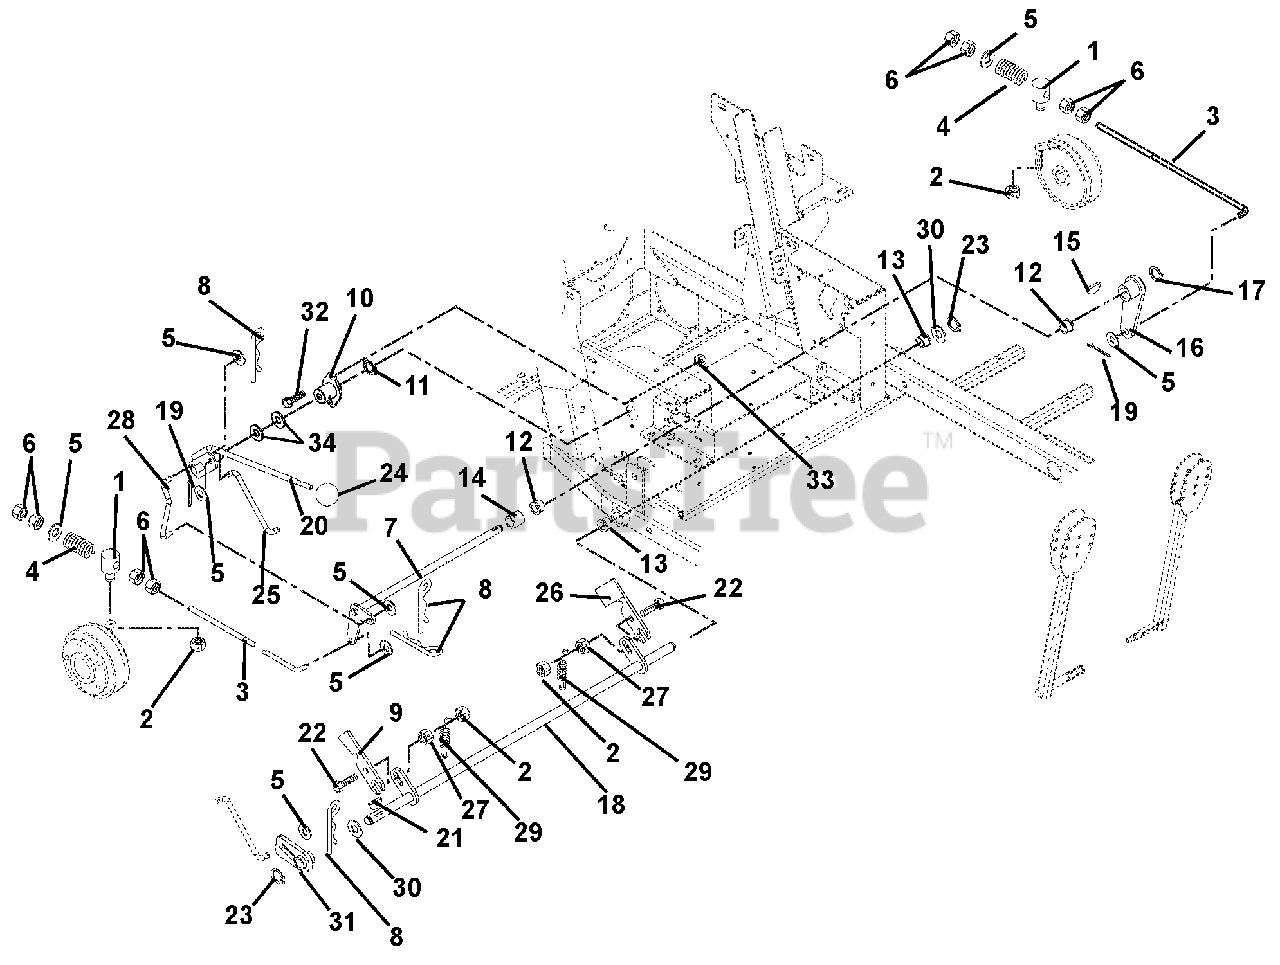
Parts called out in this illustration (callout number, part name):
1	Pivot, Brake Rod
2	Nut, Locking Center .31-18
3	PTO Link Rod
4	Spring, Compression .142 x .710 x 1.75
5	Washer, Flat Steel .406 x .812 x .065
6	Nut, Hex .38-16
7	Shaft, Brake Cross
8	Pin, Hair
9	Slide, Interlocking Brake
10	Bushing, Flange
11	Ring, Retaining External .625 x .05
12	Bushing, Flange Nylon .762 x 1.00 x .58 x 1.48
13	Bushing, Flange .515 x .75 x .745 x 1.00
14	Bushing, Sleeve .75 x 1.00 x .75
15	Key, Woodruff .19 x .75 Hard #9
16	Arm, Brake
17	Ring, Retaining External .69 x .077
18	Weldment, Mechanical Brake
19	Pin, Cotter External .09 x .75
20	Weldment, Brake Actuating
21	Key, Woodruff .13 x .63
22	Bolt, Round Head Square Neck .31-18 x 1.25 Grade 5
23	Ring, Retaining External .50 x .05
24	Knob, Steering Lock
25	Linkage, Brake Actuating
26	Interlock, Safety Switch
27	Nut, Locking Top Flange .31-18
28	Linkage, Brake Actuating
29	Spring, Tension .048 x .44 x 1.75
30	Washer, Flat Steel .505 x 1.00 x .062
31	Weldment, Parking Brake Hub
32	Bolt, Hex .31-18 x .75 Grade 5
33	Nut, Locking Top Flange .31-18
34	Washer, Flat Steel .630 x 1.25 x .062
